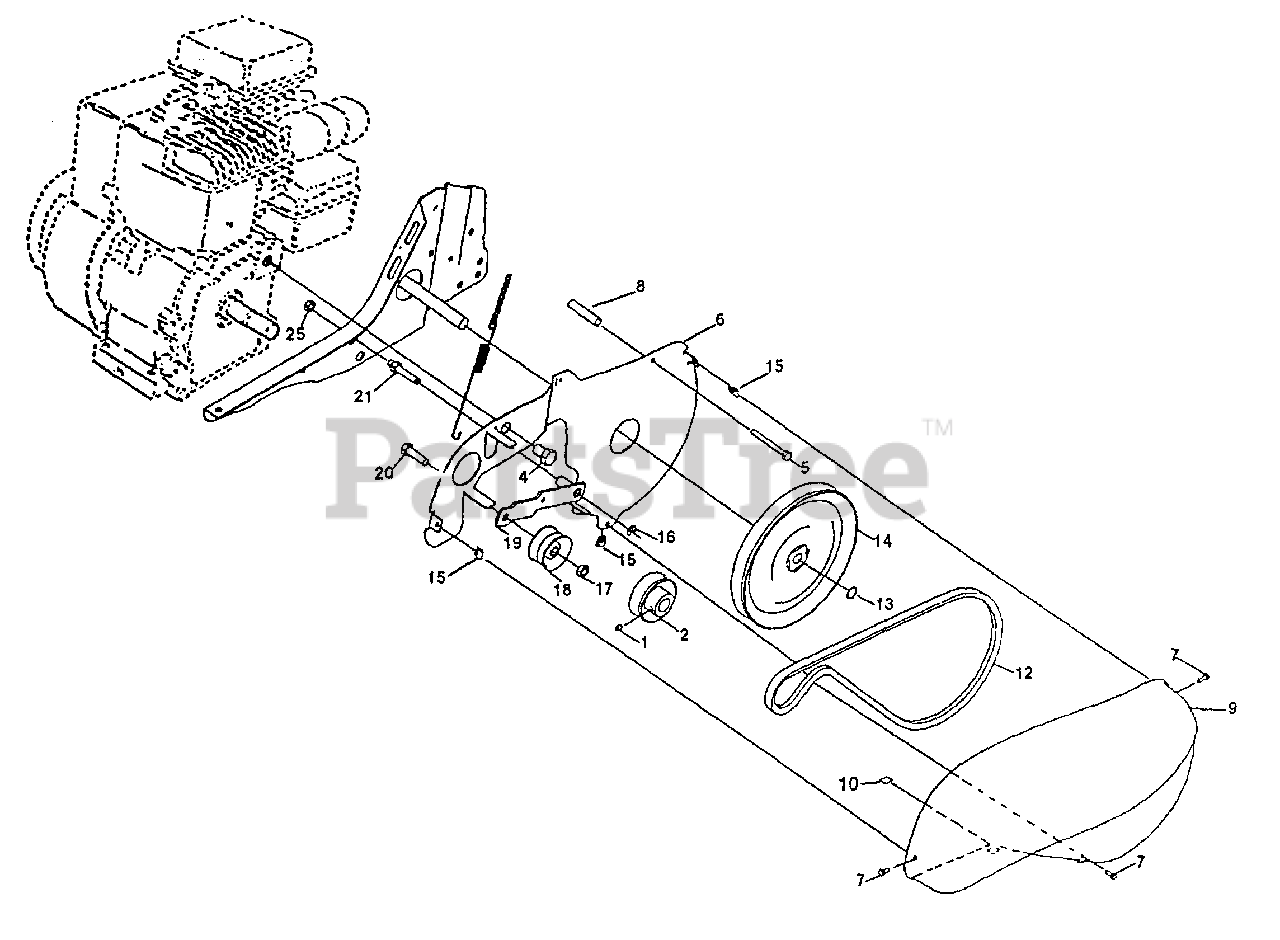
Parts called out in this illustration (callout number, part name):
1	Screw, Set, Forged Socket, Headless 5/16-18 x 3/8
2	Pulley, Engine
4	Bolt, Hex 1/2-20 x 3/4
5	Bolt Thd Roller 1/4-20 x 2-1/2
6	Shield Inner Belt Guard
7	Screw Hex Wsh Head #8-18 x 1/2
8	Spacer Split .523 x .718 x 2
9	Guard, Belt
10	Pad, Idler
12	V-Belt
13	Ring, Retainer (AYP part number)
14	Pulley, Transmission
15	Nut J Clip #8
16	Ring, Klip
17	Nut, Hex, Jam 3/8-16
18	Pulley, Idler
19	Idler Arm Assembly
20	Bolt, Hex 3/8-16 x 1-1/4
21	Shaft, Idler Arm
25	Nut, Hex, Jam 5/16-18
